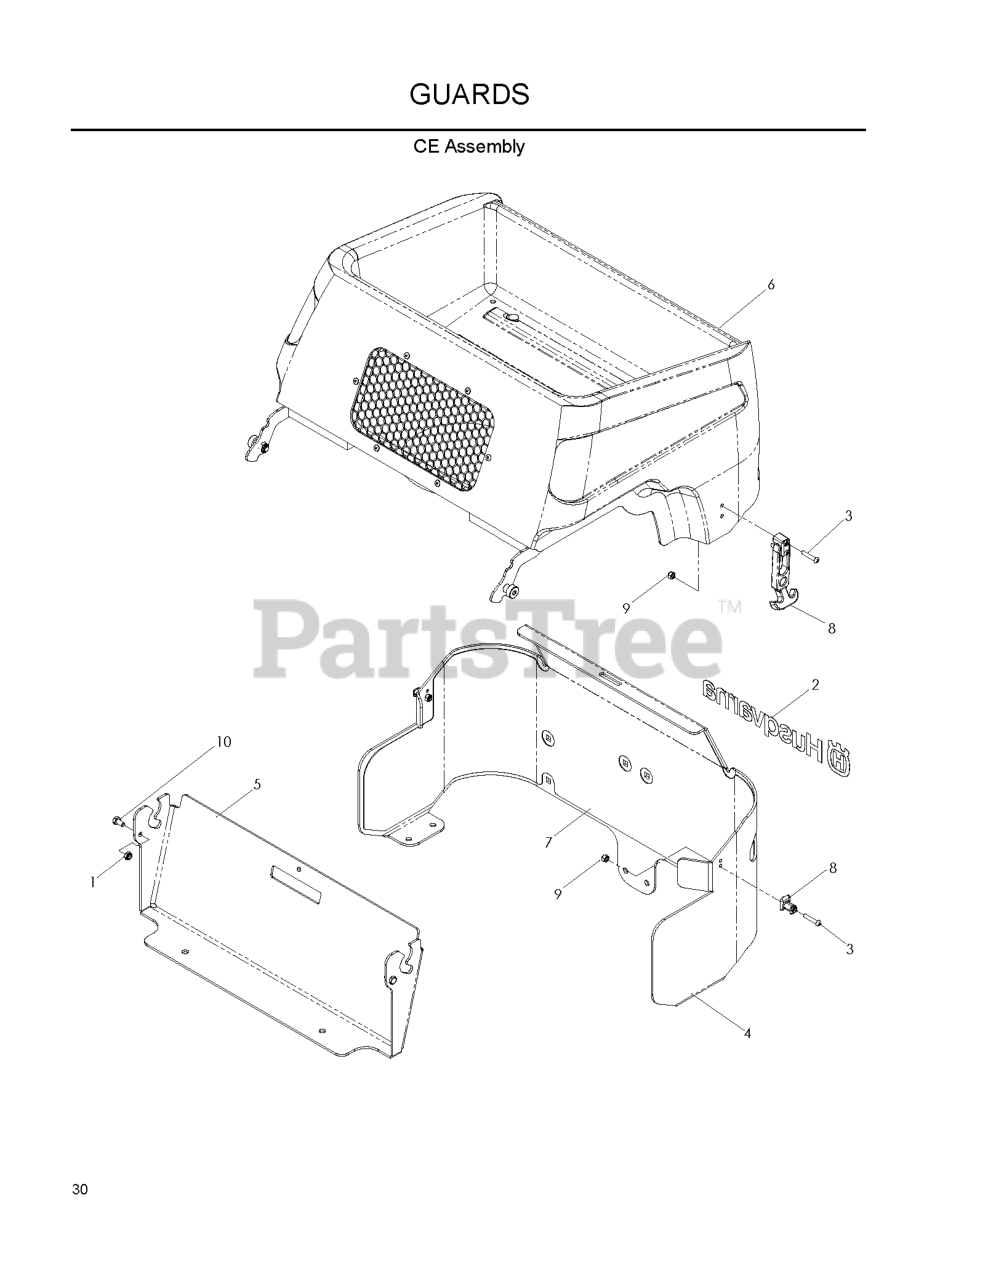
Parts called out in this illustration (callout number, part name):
1	JAM NUT 1/4C (2 2 PW01)
2	DECAL, HUSQ 12" BLUE
3	SCR, #10-24 X 1-1/8
4	REAR GUARD
4	REAR GUARD, ORANGE
5	FRONT SUPPORT
6	HOOD ASSEMBLY, Z
7	BARRIER, HEAT
8	DRAW LATCH, FLEXIBLE T-HANDLE
9	NUT 10-24 NYLOC
10	HCS 1/4-20.
